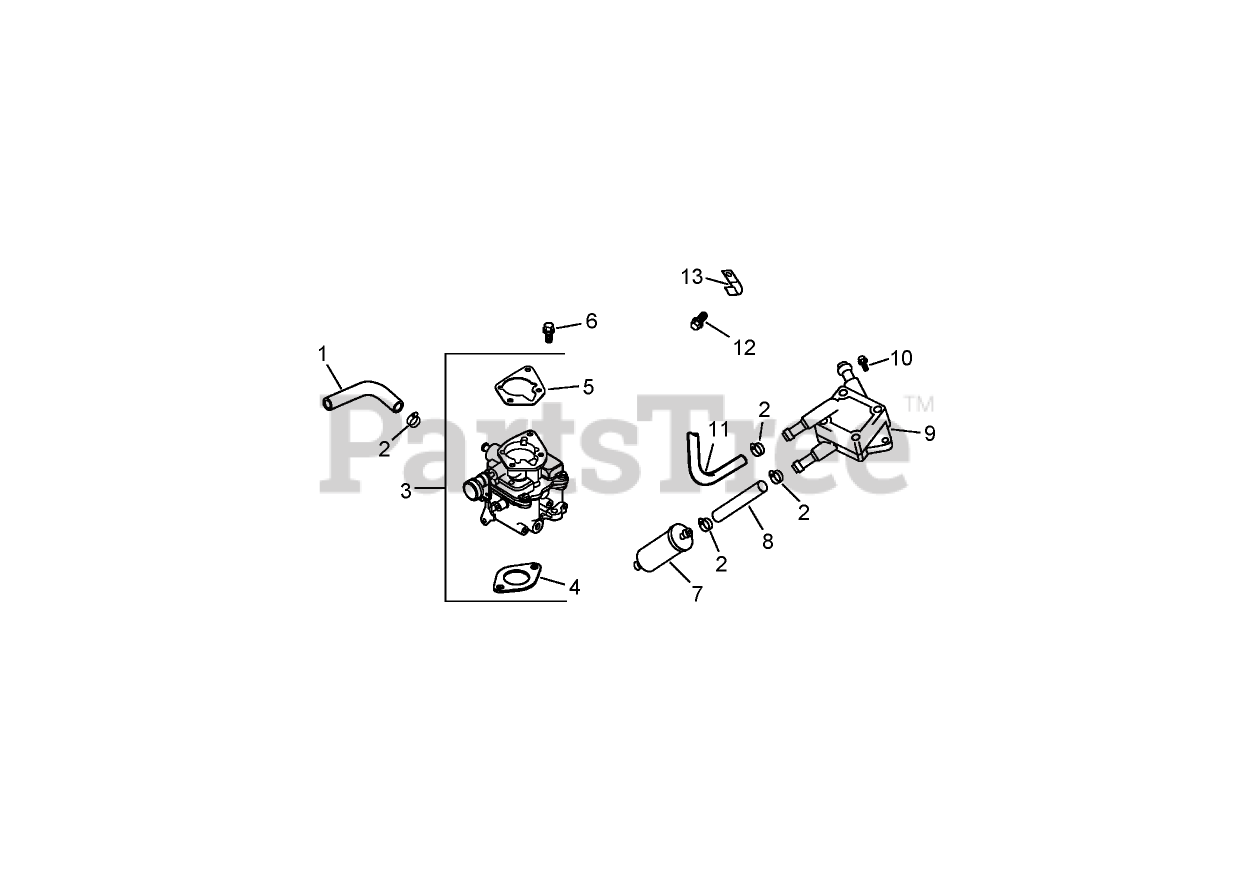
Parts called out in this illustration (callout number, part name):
1	Line-Fuel, 9-1/2in (pump to carb)
2	CLAMP-HOSE, SPRING (1/2)
3	Carburetor Kit (Includes 4, 5)
4	GASKET-CARBURETOR
5	GASKET-BASE, AIR CLEANER
6	SCREW-FLANGE (M6X1.0X30)
7	FILTER-FUEL
8	Line-Fuel, 90 Deg. Elbow
9	PUMP-FUEL
10	SCREW-TAP (M6X1.7X18)
11	Line-Fuel, 15in (fitting to pump)
12	Screw-HF (M6x1.0x12)
13	CLIP-CABLE
